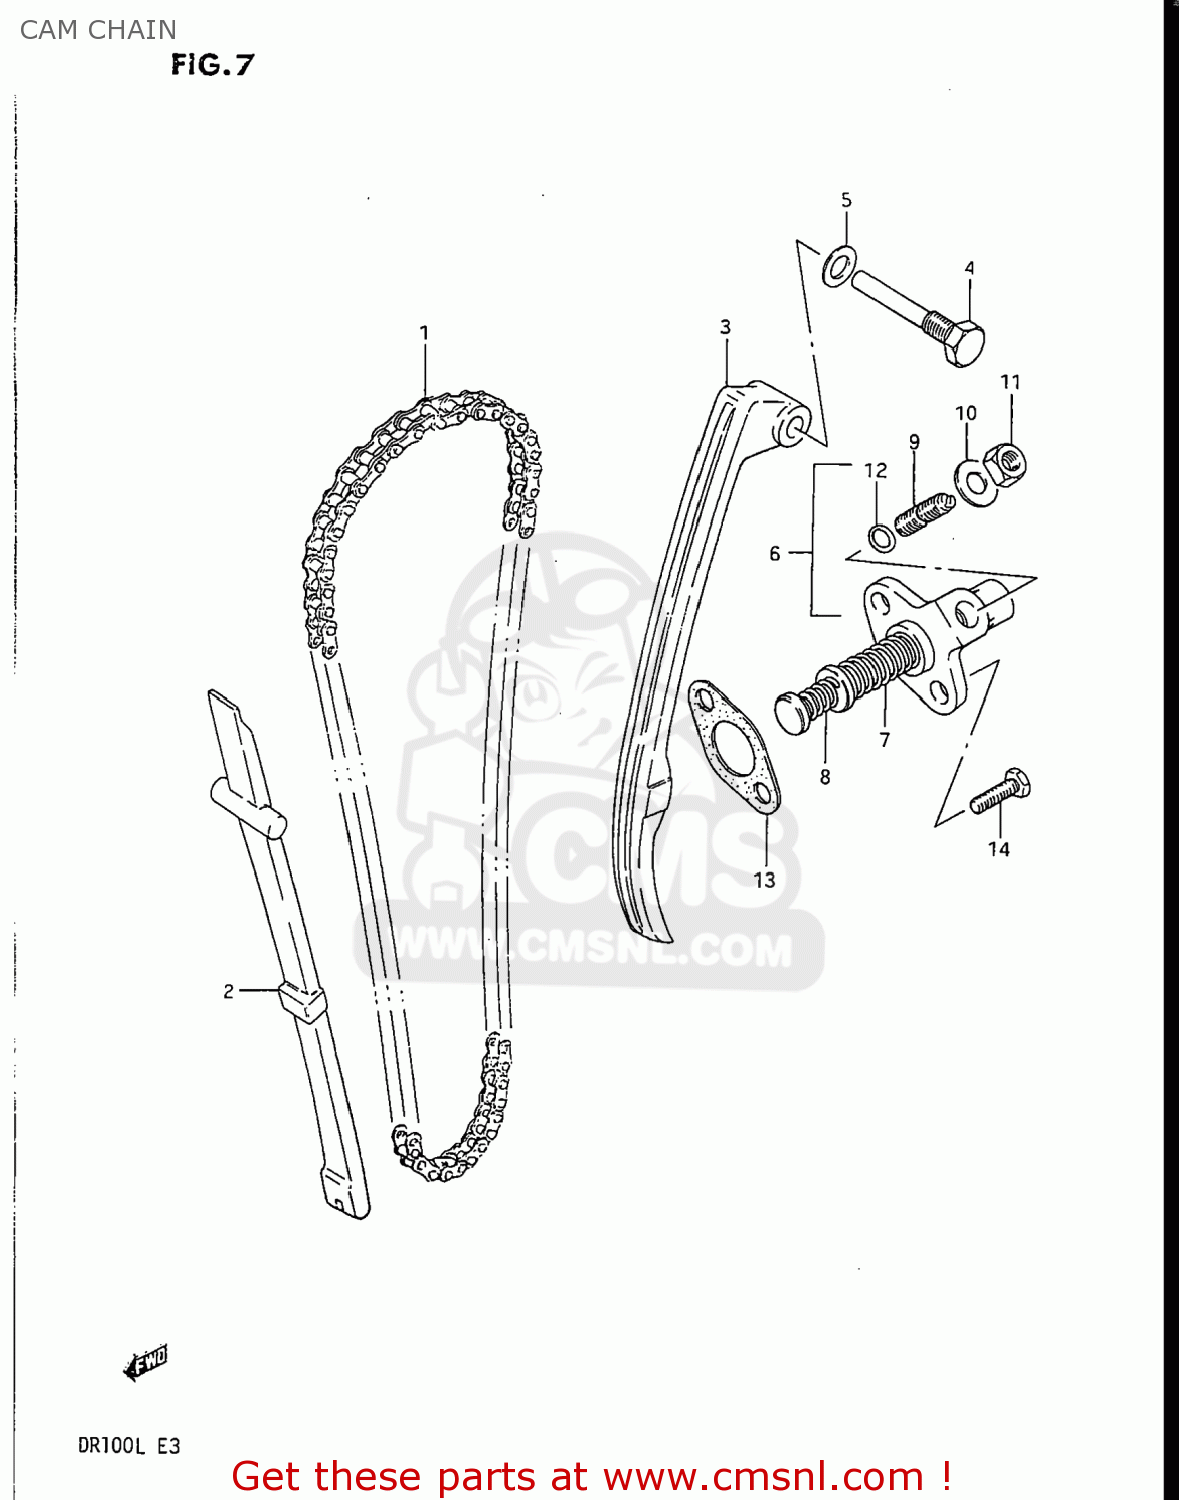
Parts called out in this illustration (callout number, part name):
1	CHAIN,CAMSHAFT DRIVE
2	GUIDE,CAM CHAIN
3	TENSIONER,CAM CHAIN
4	BOLT,CAM CHAIN TENSIONER
5	GASKET 8.2X14X1 (NAS)
6	ADJUSTER ASSEMBLY,TENSIONER
7	SPRING
8	SPRING
9	SCREW
10	WASHER
11	NUT
12	O RING(D:1.9,ID:5.7)
13	GASKET,TENSIONER ADJUSTER (NAS)
14	BOLT
